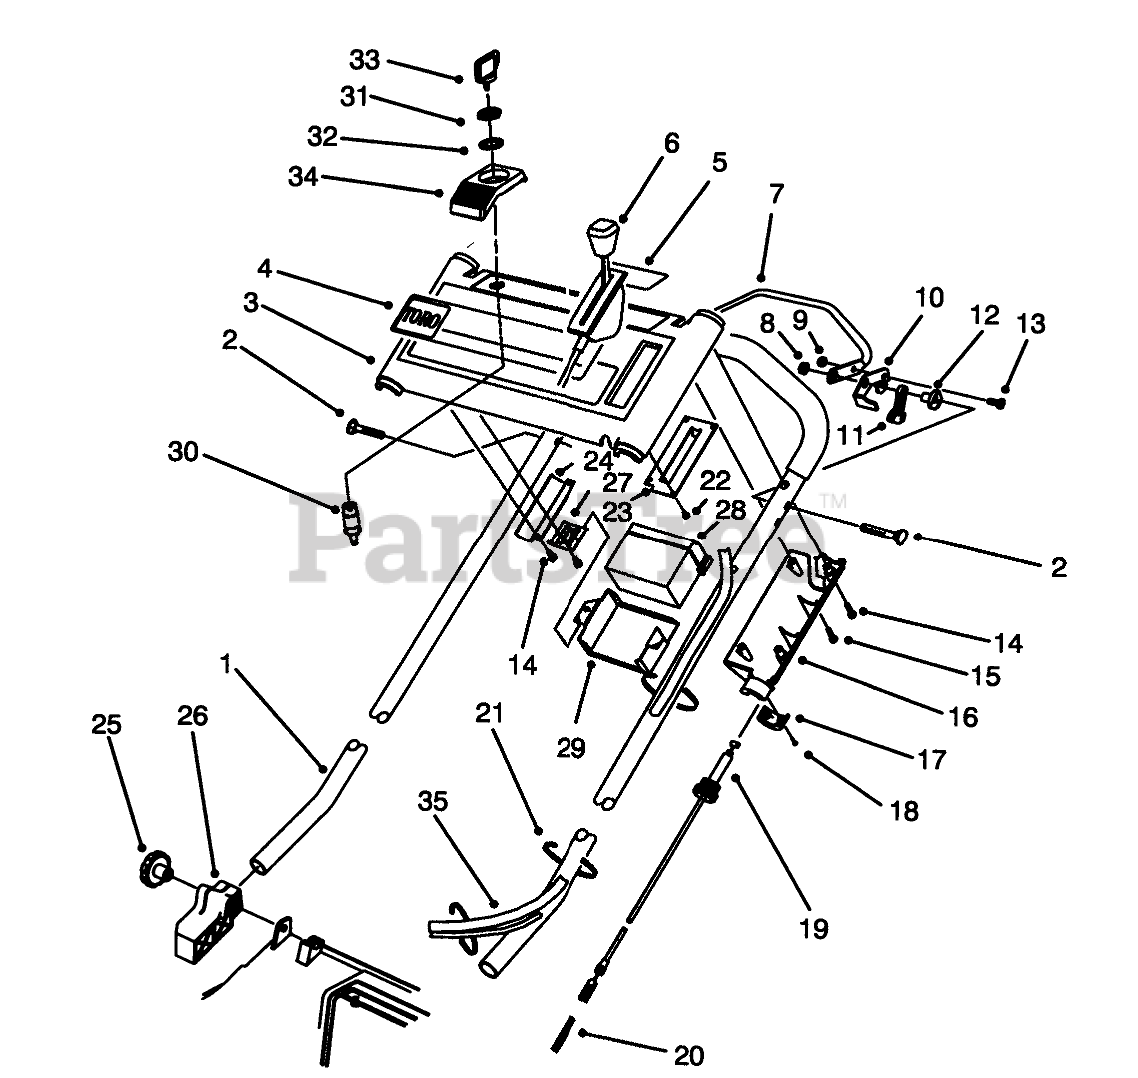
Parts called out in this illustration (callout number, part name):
1	HANDLE (DIPPED)
2	SCREW-HANDLE
3	Panel-Control (Incl Ref. #4, & 5)
4	DECAL - PANEL KEY
5	DECAL - PANEL
6	THROTTLE CONTROL
7	CONTROL BAR
8	NUT-LOCK, NI
9	NUT-LOCK, NI
10	LEVER-CONTROL
11	LEVER-TRACTION
12	SPACER-SUPPORT
13	SCREW-HH
14	SCREW-PPH, PLASTITE
15	Screw
16	Cover-Throttle Lower
17	LOWER THROTTLE CAP
18	#4-14X.62 PLASTITE SCW
19	TRACTION CABLE
20	SPRING-COMPRESSION
21	TIE-CABLE
22	#6-19X.25 PLASK FORM SC
23	THROTTLE PLATE
24	Bracket-Panel
26	MOUNT-HANDLE, RH
27	BATTERY BRACKET
28	BATTERY ASSEMBLY
29	Retainer-Battery
30	Switch-Starter (Incl.Ref.#31,&32)
31	NUT-HH
32	WASHER-TOOTH, INTERNAL
33	KEY-IGNITION
34	IGNITION SWITCH BRACKET
35	Harness-Wire
